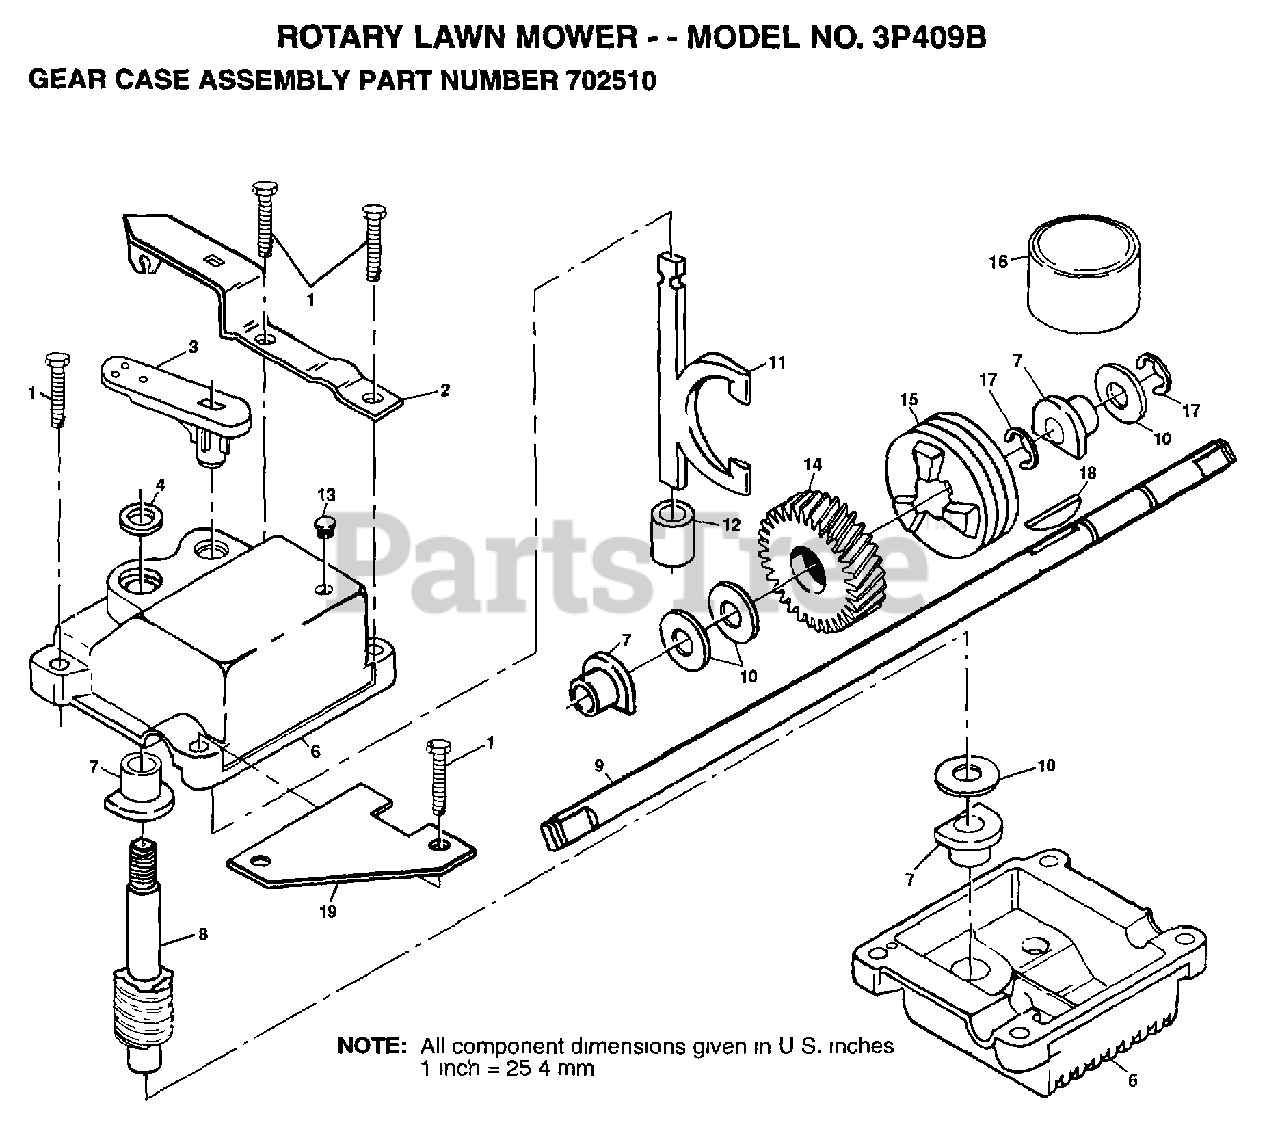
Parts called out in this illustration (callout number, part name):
1	SCREW.1/4-20
3	SHIFTER
4	SEAL
6	KIT GEARCASE HALV
7	BEARING
8	SHAFT.WORM
9	SHAFT.DRIVE.SD
10	THRUST WASHER
11	CLUTCH YOKE
12	BUSHING.GEAR BOX
13	PLUG PM
14	GEAR.HELICAL
15	CLUTCH JAW
17	RING T
18	HI PRO KEY
